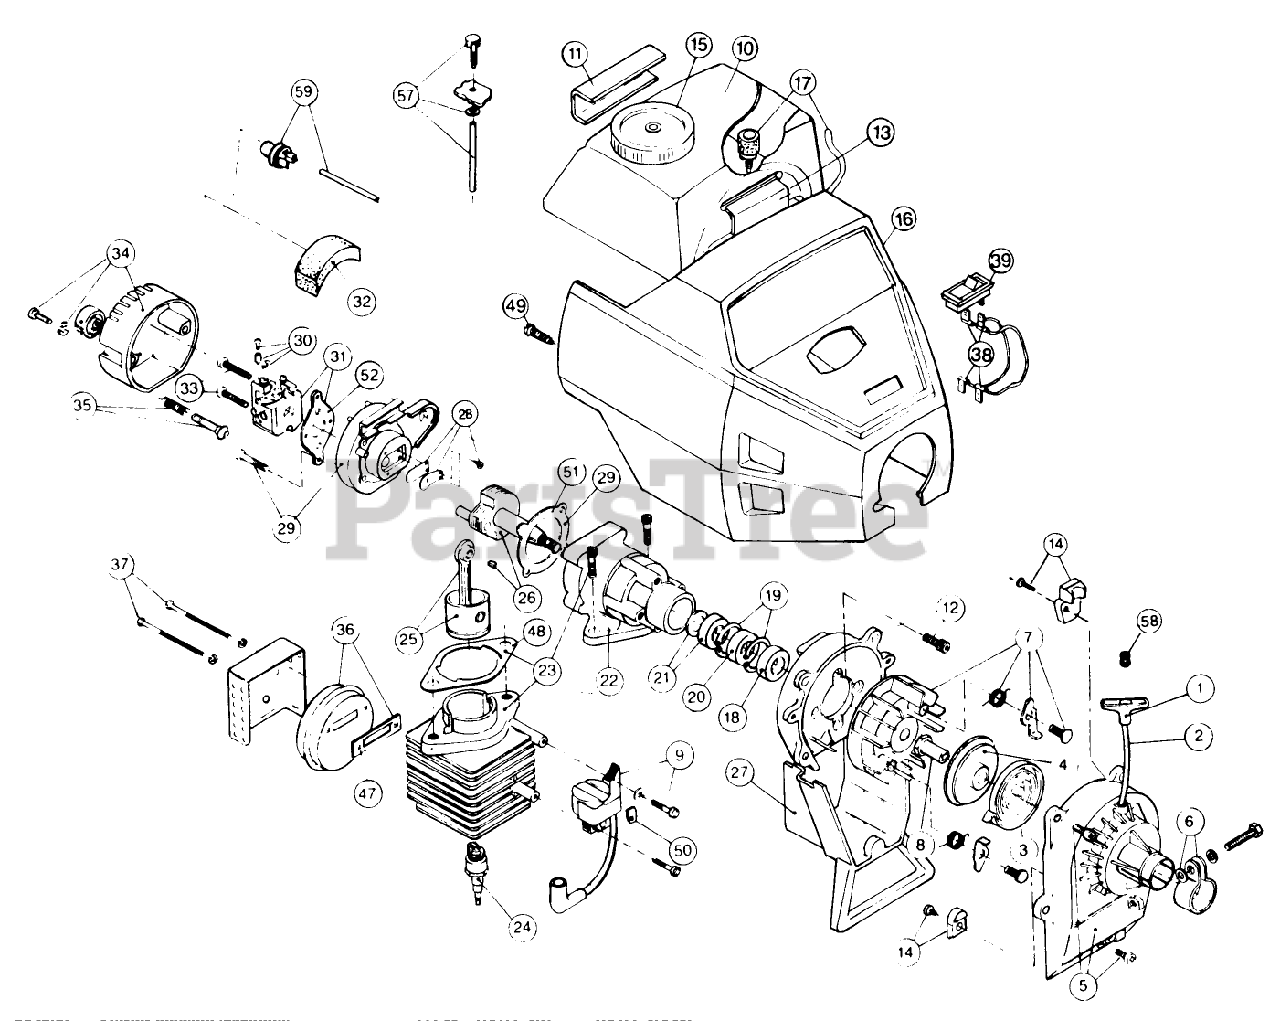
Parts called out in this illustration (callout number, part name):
3	RECOIL SPRING
8	SQUARE DRIVE NUT
10	Fuel tank
11	REAR MOUNTING PAD
12	SHROUD ASM
13	FRONT MOUNTING PAD
17	FUEL LINE ASM
18	Outer bearing
20	SEAL
21	INNER BEARING ASM
24	SPARK PLUG
30	THROTTLE ADJ ASM
37	MUFFLER MOUNTING BOLTS
45	SHORT BLOCK ASM
52	CARB.GASKET
56	FLYWHEEL KEY (10-PK)
57	FUEL RETURN LINE ASM
